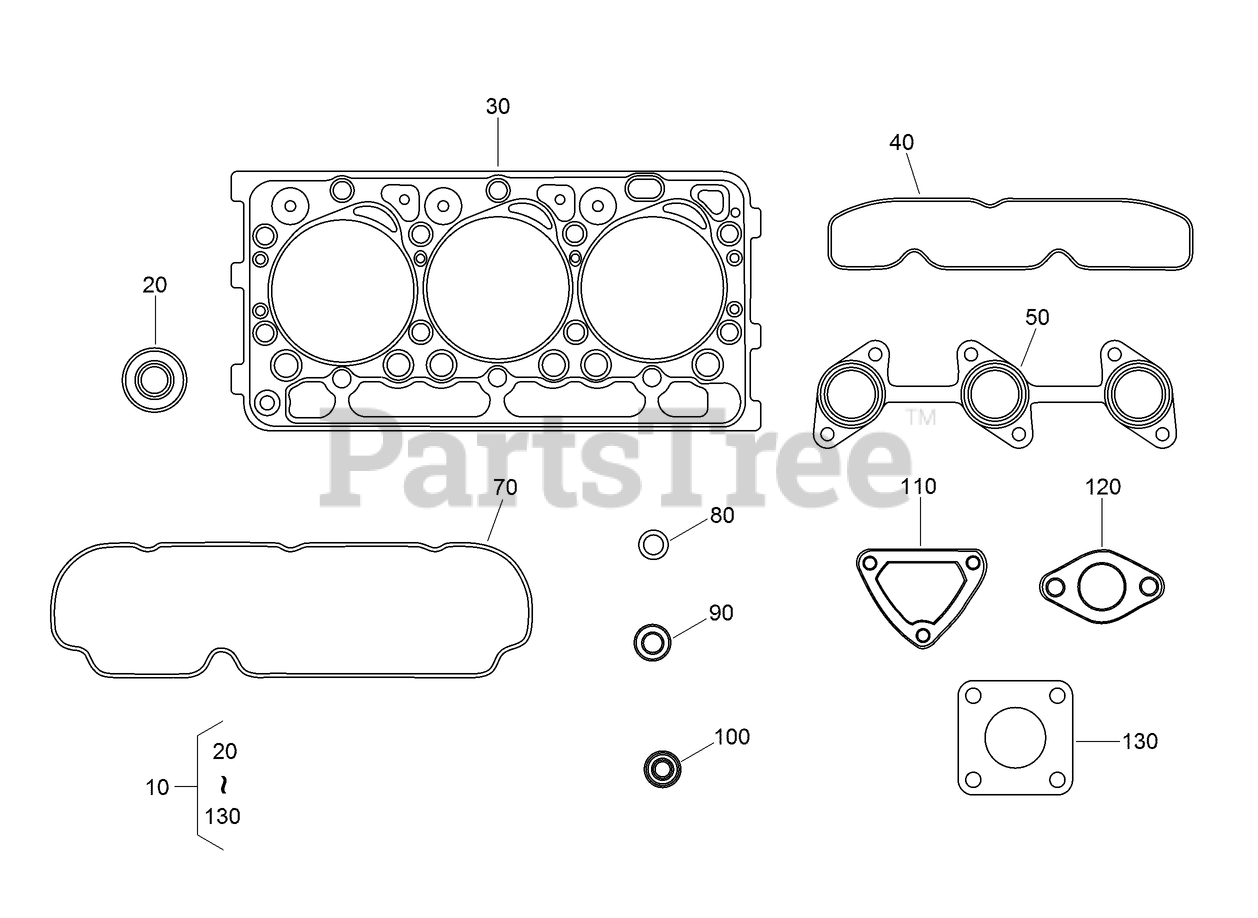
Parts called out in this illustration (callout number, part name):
20	SEAL-STEM, VALVE
30	GASKET-HEAD, CYLINDER
40	GASKET-MANIFOLD, INTAKE
50	GASKET-MANIFOLD, EXHAUST
70	GASKET-COVER, HEAD
80	O-RING
90	GASKET
100	SEAL-HEAT
110	GASKET-FLANGE, WATER
120	GASKET-THERMOSTAT
130	GASKET-MUFFLER
